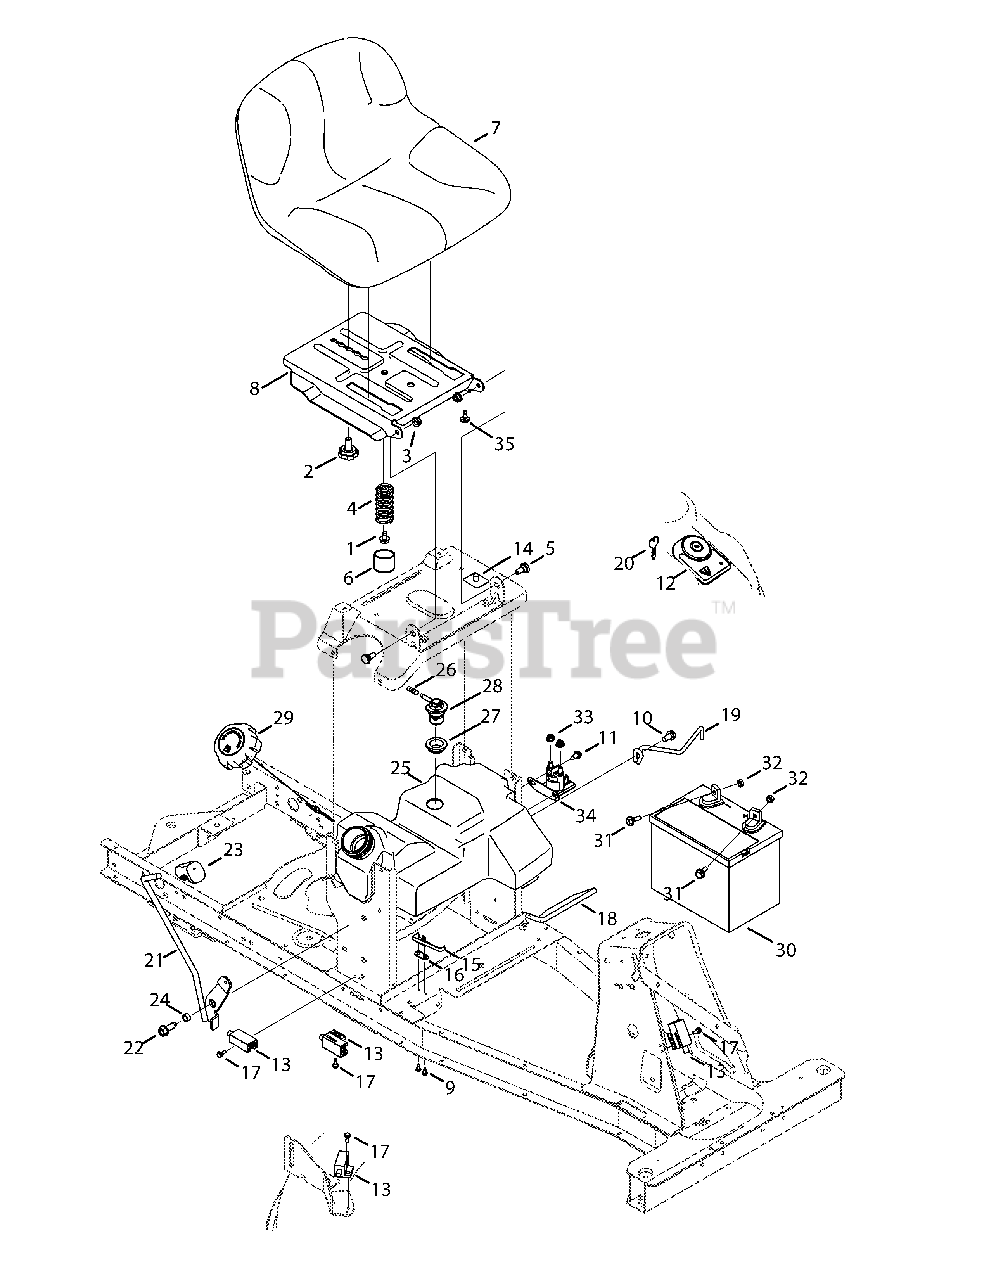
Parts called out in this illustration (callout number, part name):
1	Tap Screw, 5/16-18, 0.500
2	Knob, 3/8-16, .875
3	Flange Lock Nut, 5/16-18
4	Seat Spring
5	Shldr Spacer, .435 X .178-5/16 X .56
6	Vinyl Cap, 1.188 x 1.00
7	Seat, Med. Back
8	Seat Pivot Bracket
9	Screw, #8
10	Tap Screw, 5/16-18, .750
11	Tap Screw, 1/4-20, .625
12	Key Switch, RMC
13	Interlock Switch
14	Seat Switch
15	Switch Spring
16	Insulator Plate
17	Shoulder Screw, #10-32, .500
18	Battery Rod
19	Battery Hold Down Bracket
20	Key, Assembly
21	PTO Handle Assembly
22	Tap Screw, 3/8-16, 1.000
23	Handle Grip, 3/8
24	Spacer, .380 ID x .50 OD x .265
25	Fuel Tank, 1-3 Gal.
26	Hose Vent, 3/16 EPA
27	Rubber Grommet
28	Rollover Valve
29	Fuel Cap
30	Battery, 155 CCA
31	Screw, Shoulder, .250 x .150
32	Nut, Sems, 1/4-20
33	Flange Lock Nut, 1/4-20
34	Solienoid, 12v
35	Rubber Bumper, .63 Dia
